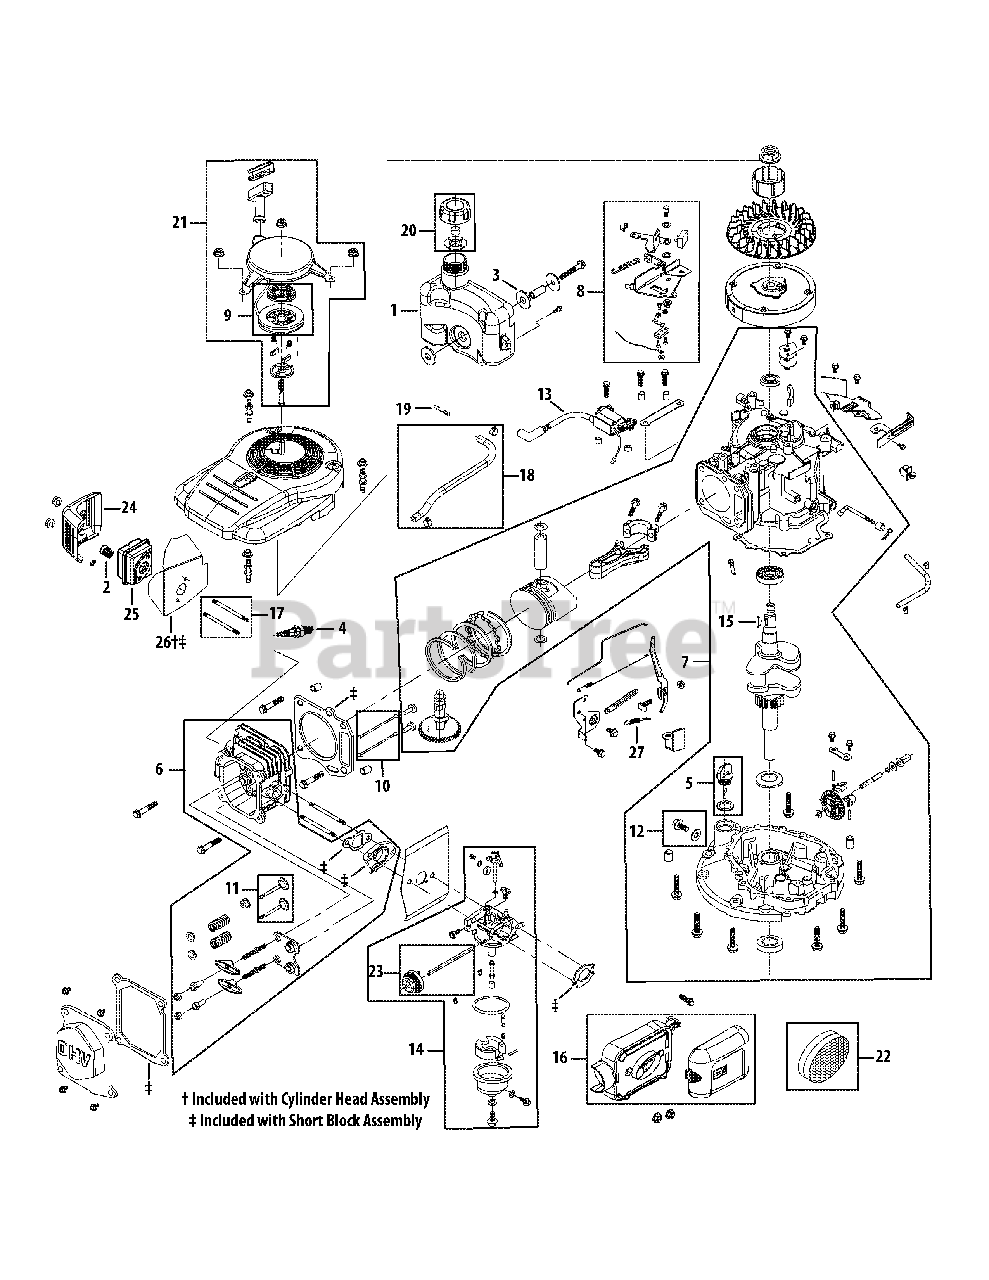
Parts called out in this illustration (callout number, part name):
1	Fuel Tank
2	Spark Arrestor
3	Rubber Fuel Tank Mounting Washer
4	Spark Plug
5	Dipstick Assembly
6	Cylinder Head Assembly
7	Short Block Assembly
8	Stop Switch and Brake Assembly
9	Recoil Spring and Pulley Assembly
10	Push Rod Kit
11	Valve Kit
12	Oil Drain Plug and Washer Assembly
13	Ignition Coil
14	Carburetor Assembly
15	Flywheel Key
16	Air Cleaner Housing Assembly Complete
17	Muffler Stud Assembly
18	Fuel Line Kit - Inc. hose & clamps
19	Fuel Filter
20	Fuel Cap Assembly
21	Recoil Starter Assembly
22	Air Filter
23	Primer Assembly
24	Muffler Shield
25	Muffler Assembly
26	Muffler Gasket /Heat Shield
27	Governor Return Spring
